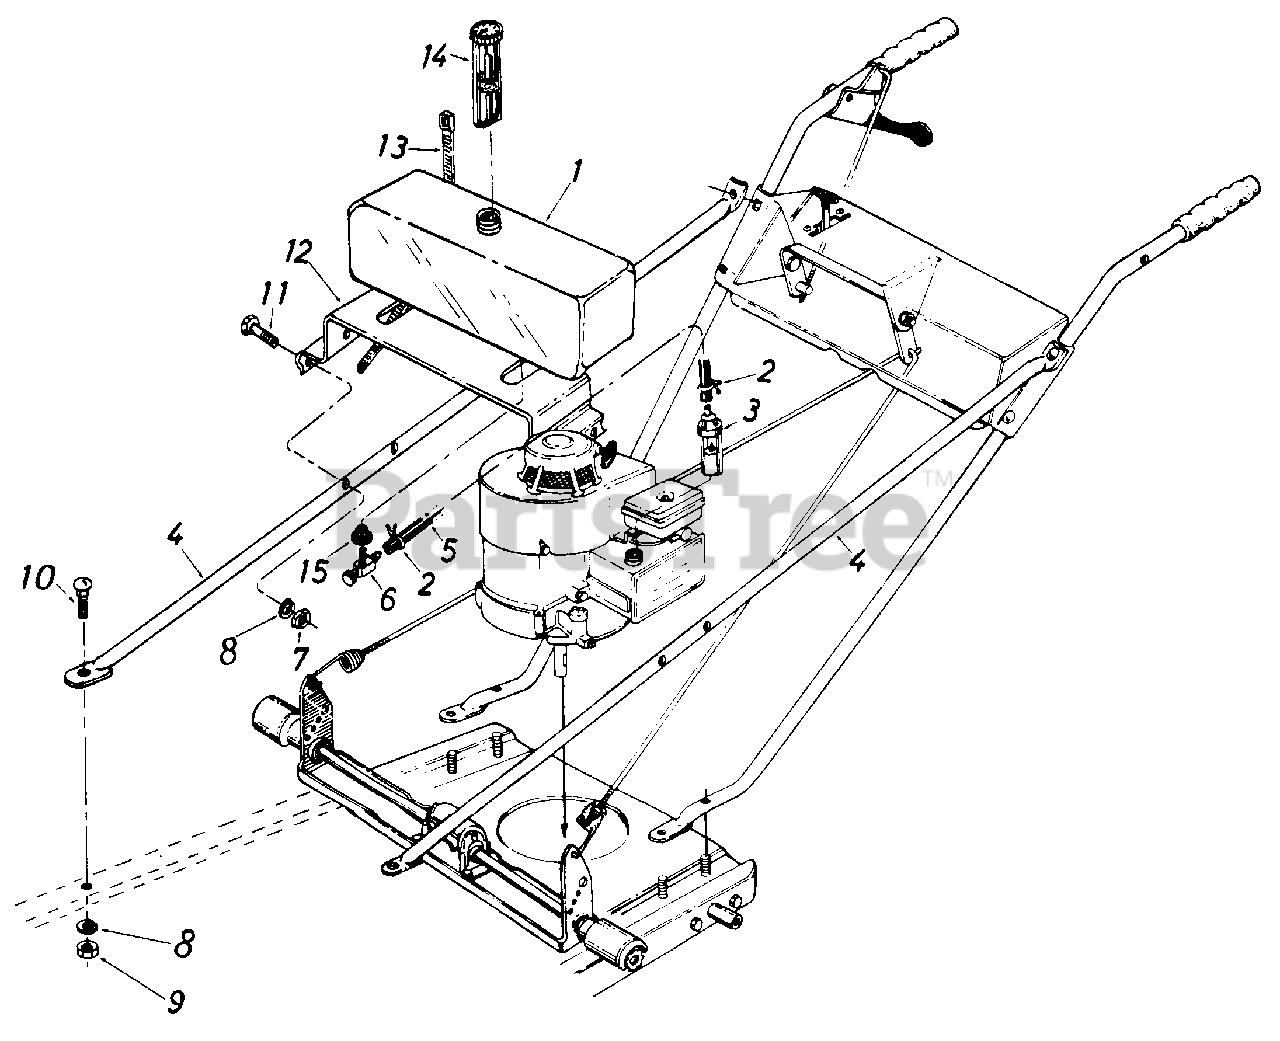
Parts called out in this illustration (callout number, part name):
2	Hose Clamp 3/8" I.D.
3	Fuel Control Valve
4	Strut
5	Fuel Line
6	Fuel Tank Fitting
7	Hex Nut 5/16-24" Thd.*
8	L-Wash. 5/16" I.D.*
9	Hex Nut 5/16-18" Thd.*
10	Carriage Bolt 5/16-18 x .62" Lg.*
11	Hex Bolt 5/16-24 x 1.25" Lg.*
12	Fuel Tank Mntg. Brk't.
13	Cable Tie 30.6" Lg.
15	Bushing
